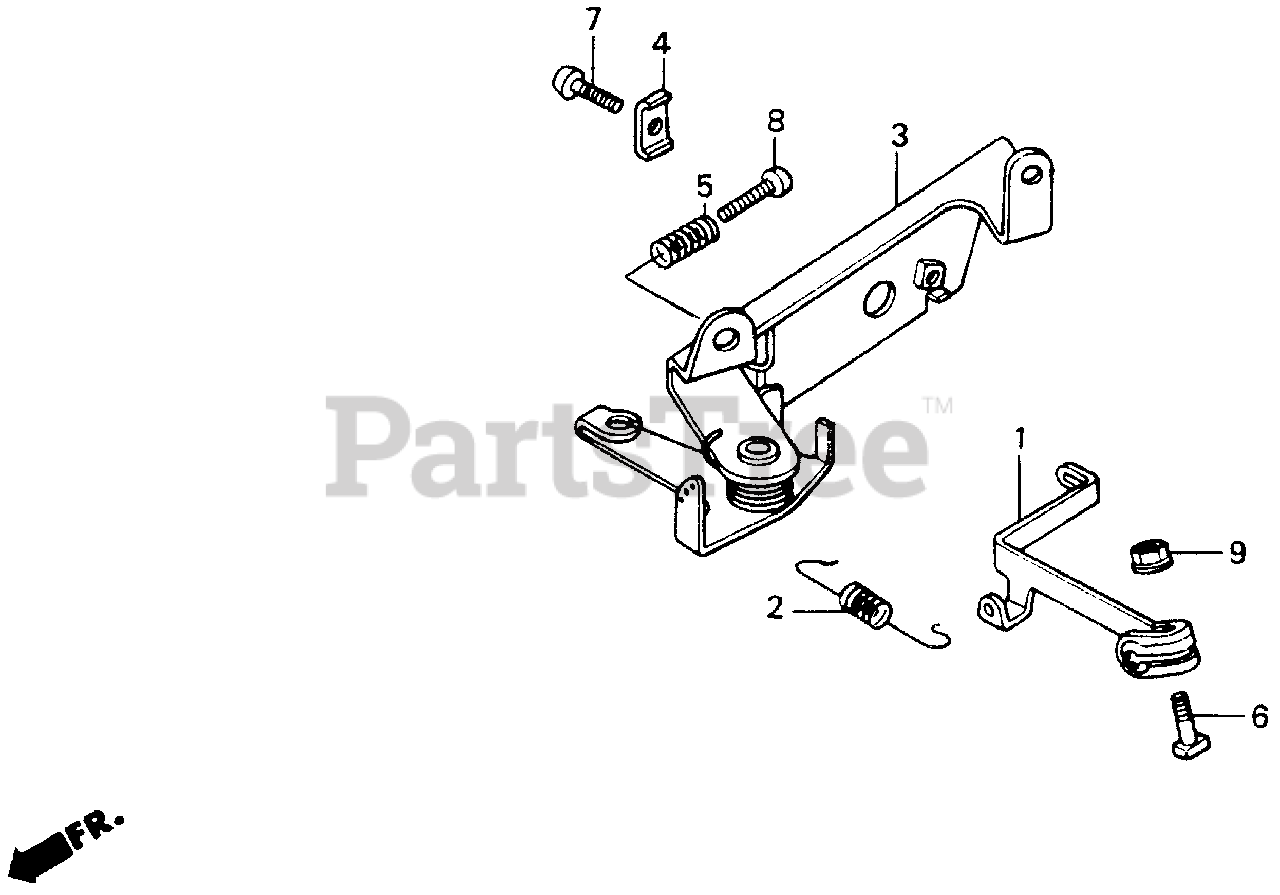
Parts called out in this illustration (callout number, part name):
1	ARM, GOVERNOR (NOT AVAILABLE)
2	SPRING, GOVERNOR
4	HOLDER, CABLE
5	SPRING, CONTROL ADJUSTING
6	BOLT, GOVERNOR ARM
7	SCREW, PAN (5X16)
8	SCREW, PAN (5X20)
9	NUT, FLANGE (6MM)
